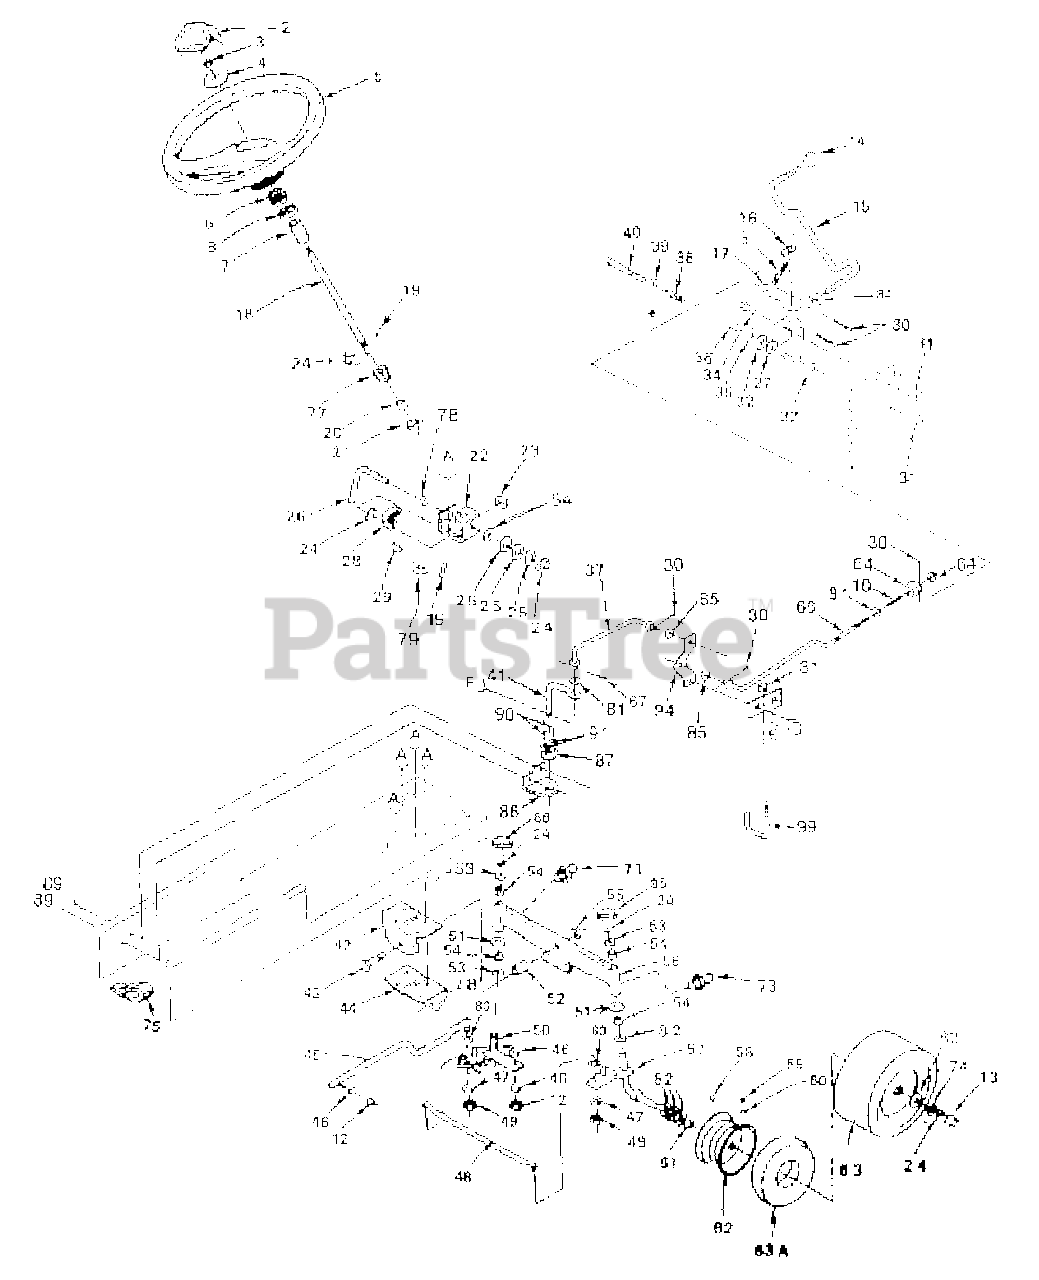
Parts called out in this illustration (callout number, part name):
2	Insert - Steering Wheel
5	Wheel Steering
6	Adapter - Steering Wheel
10	Spring - Compression
12	Nut, Fin Hex 3/8 - 24 UNF
13	Cap- Hub- Front
14	Knob.Gear Shift
15	Rod - Control
16	Spring - Torsion
17	Bracket - Control Rod
18	Shaft - Steering
19	Pin - Drive 3/16 x 1
22	Bracket - Steering
23	Washer 21/32 x 1 - 1/4 x 16 Ga.
25	Bearing - Thrust
26	Rod - Steering
27	Washer- Phenolic
28	Gear - Sector
29	Key-Woodruff
32	Washer- Friction
33	Washer 13/32 x 13/16 x 12 Ga.
34	Bolt - Hex Shoulder 3/8 - 16 x 1 -3/8
35	Washer 21/32 x 1 - 1/4 x 16 Ga.
37	Link - Control
38	Spring - Compression
41	Lever - Pump Control
42	Support - Saddle - Rear
44	Support. Saddle. Front
48	Rod-Tie
49	Nut- Hex 5/16- 24
50	Spindle L.H.
51	Washer 27/32 x 1 - 1/4 x 16 Ga.
52	Spacer
53	Hardened Washer
56	Axle. Front
57	Spindle - R H
58	Fitting- Grease
59	Stem - Valve
60	Cap - Valve
62	Rim 6" Front
63	Tire- Front
63A	Tube Tire Front
66	Rod - Adjustable Control
67	Clip, Hairpin
73	Fitting - Grease
74	Washer 25/32 x 1 - 5/8 x 16 Ga.
75	Clip-Insulated
77	Gear- Pinion
78	Nyliner, Snap- In
79	Washer- Hardened
80	Washer 13/32 x 13/16 x 16 ga.
82	Washer 25/32 x 1 1/4 x 16 Ga.
84	Washer 15/32 x 15/16 x 16 Ga.
85	Washer, Spring
86	Spindle.cap.
87	Guide. Control
88	Bracket, Control Guide
89	Screw, Hex Washer Thd Rol 5/16 -18 x 3/4 TYTT
90	Screw, Tap Hex Hd. #10 - 24 UNC x 1/2TY-T
91	Washer 7/32 x 1/2 x 16 Ga.
92	Bolt,10-24x3/4
95	Bracket, Bellcrank Pivot
96	Bolt, Shoulder
99	Keeper, Centerspan
